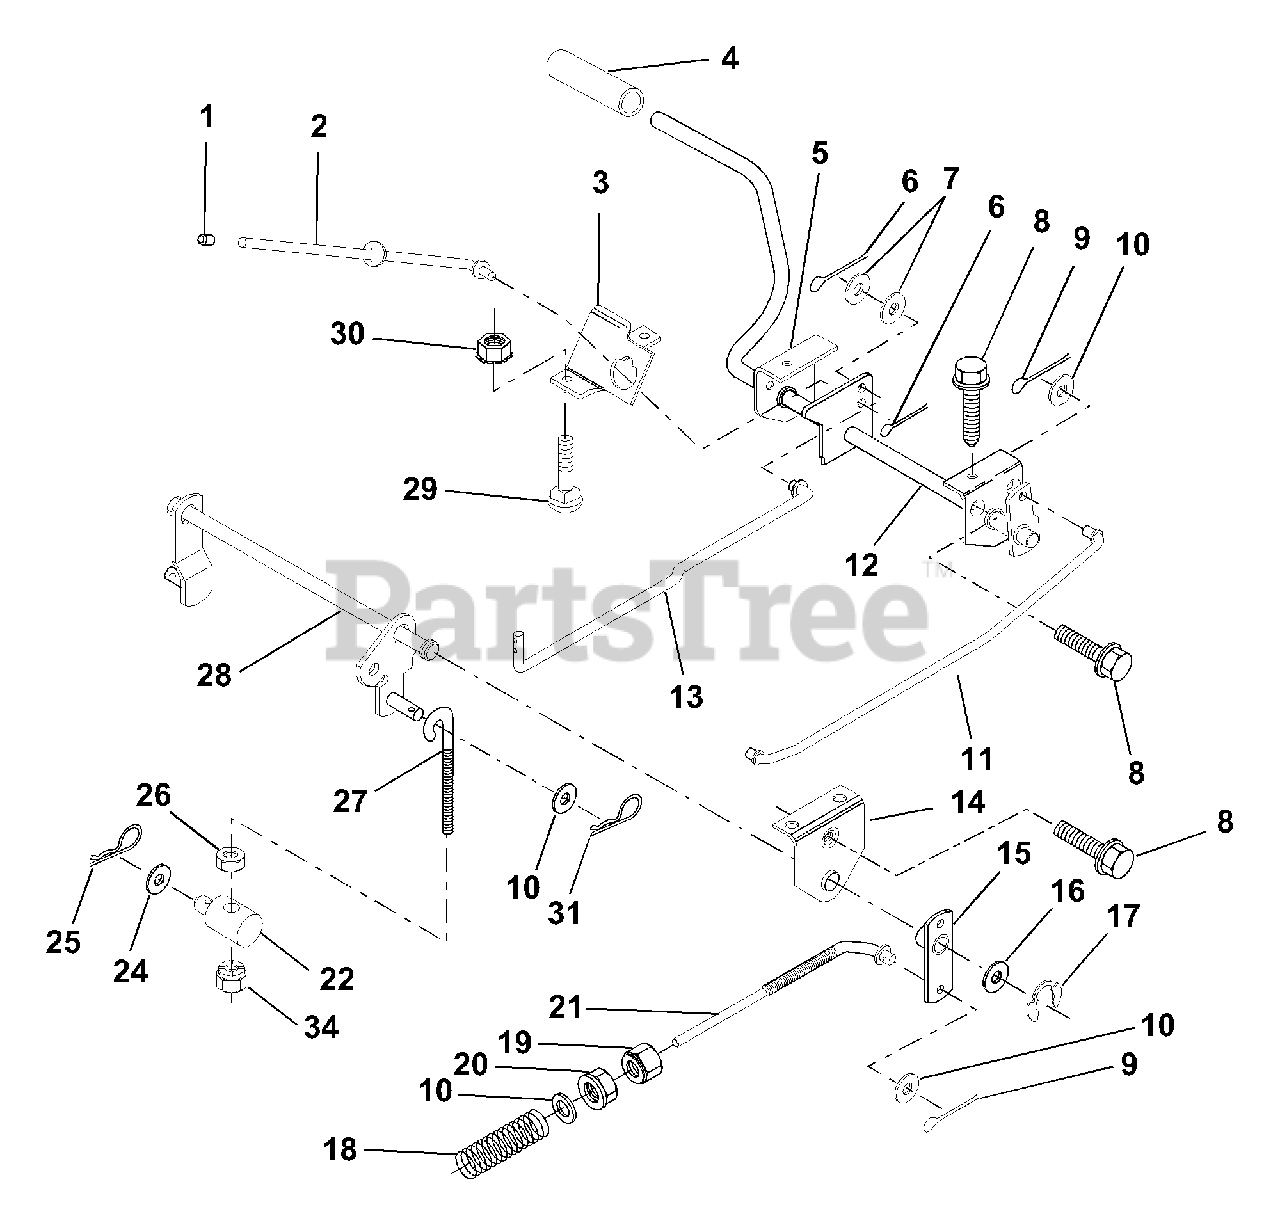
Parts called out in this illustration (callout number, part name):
1	Cap, Plunger
2	Rod, Parking Brake
3	Bracket, Parking Brake
4	Cover, Pedal
5	Bracket, Clutch/Brake Pedal, L.H.
6	Pin, Cotter 3/32 x 3/4
7	Washer 13/32 x 5/8 x 16 Ga.
8	Screw, Hex, Thd. Roll. 5/16-18 x 1/2
9	Pin, Cotter 1/8 x 3/4
10	Washer 13/32 x 13/16 x 16 Ga.
11	Rod, Brake Front
12	Assembly, Clutch/Brake Pedal
13	Rod, Clutch
14	Bracket, Lift, Shaft
15	Assembly, Brake, Pivot, Arm
16	Washer 25/32 x 1-1/8 x 16 Ga.
17	Ring, Klip
18	Spring, Brake Rod
19	Nut, Hex, Jam 3/8-16 UNC
20	Nut, Lock, hex. w/Ins. 3/8-16 INC
21	Rod, Rear Brake
22	Trunnion, Lift
24	Washer 13/32 x 1-1/4 x 12 Ga.
25	Spring, Retainer
26	Nut, Centerlock 3/8-16 UNC
27	Link, Threaded
28	Assembly, Rear Mower Lift
29	Bolt, Carriage 5/16-18 UNC x 3/4
30	Nut, Keps 5/16-16 UNC
31	Retainer Spring
34	Nut, Crownlock 3/8-16 UNC
